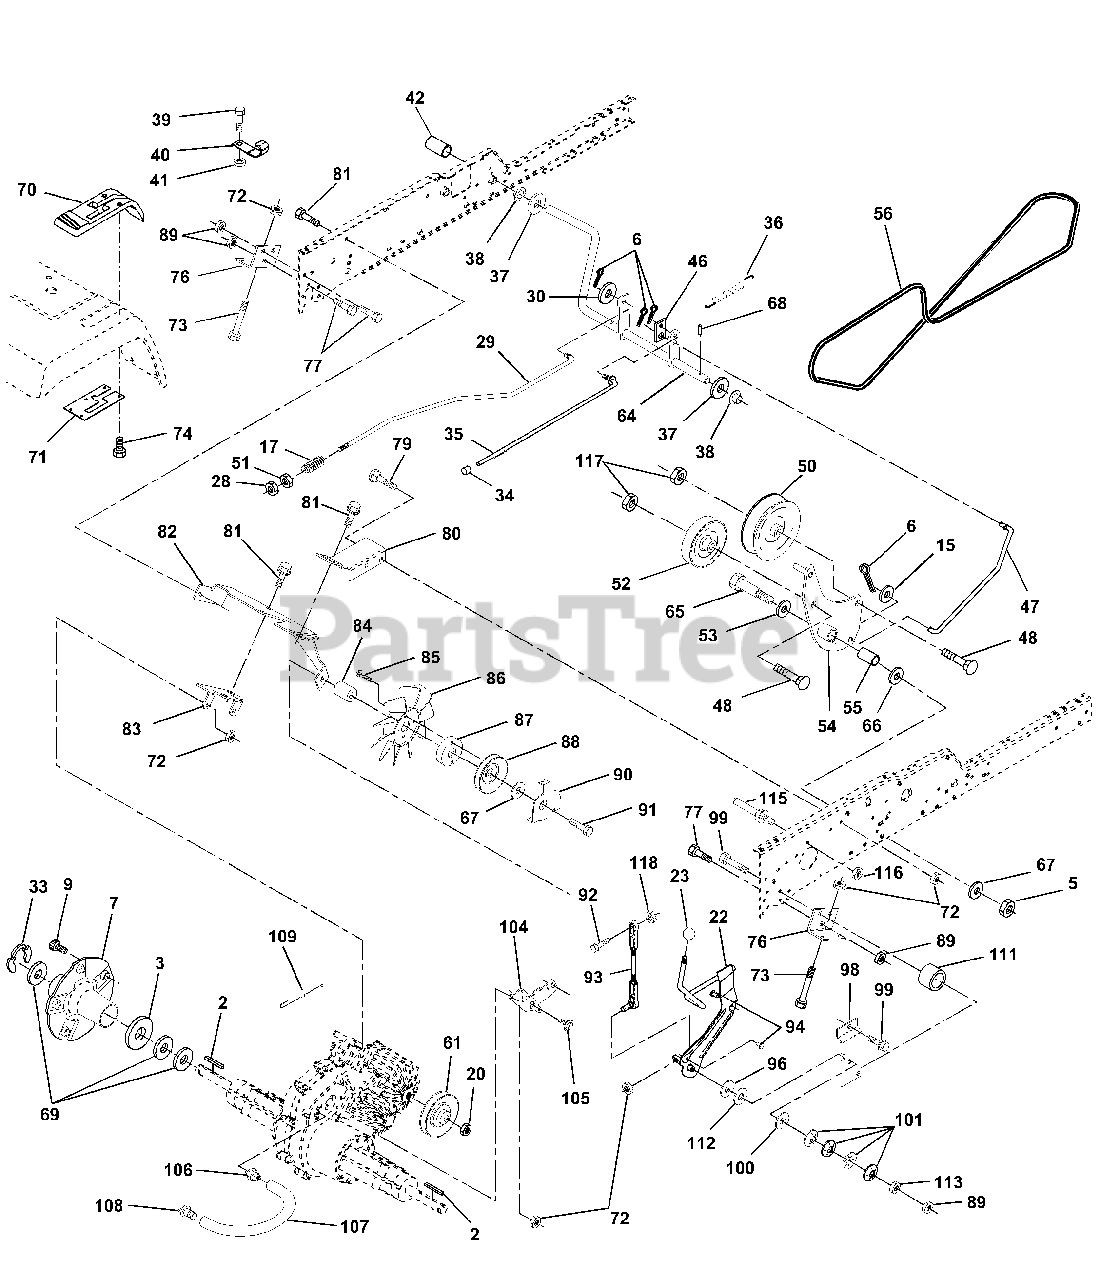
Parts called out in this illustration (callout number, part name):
2	Key 1/4 x 2.5
3	Washer Thrust Axle Harden
5	Nut Crownlock 3/8-16
6	Pin Cotter 1/8 x 3/4
7	Wheel Hub Asm.
9	Bolt Hub
15	Washer 13/32 x 13/16 x 16 Ga.
17	Spring Rod Brake
20	Nut Hex Jam Toplock 1/2-20
22	Shaft Arm Asm
28	Nut, Hex Jam 3/8-16
29	Brake Rod
30	Washer 13/32 x 1 x 16Ga
34	Cap Plunger
35	Rod Parking Brake
36	Spring Drive Ground
37	Washer 25/32 x 1-1/4 x 16 Ga.
39	Screw Fin #10-24 x 1
40	Actuator Interlock Switch
41	Nut Toplock #10-24 UNC
42	Cover Pedal
46	Retainer Spring
47	Clutch Rod
48	Bolt Carriage 3/8-16 x 1-1/2 Gr. 5
50	Pulley Idler Flat
51	Nut Lock Hex 3/8-16
52	Pulley Idler Grooved
53	Washer Hardened
54	Clutch Arm Asm
55	Bearing, Idler
61	Pulley Transaxle
64	Shaft Asm Brake Parking Clutch
65	Bolt Shoulder
66	Washer Hardened
67	Washer 13/32 x 13/16 x 12 Ga
69	Washer
70	Console Hydro Fender
71	Plate Console Shift
72	Nut Crownlock 5/16-18
73	Bolt Hex FLGHD 5/16-18 x 3 Gr 5
74	Screw, Hex Wsh Hi-Lo 1/4-1/2
76	Bracket Transaxle
77	Bolt Fin Hex 7/16-14 x 1
79	Bolt Carriage 5/16-18 x 5/8
80	Bracket Torque RH
81	Screw 3/8-16 x 3/4
82	Bracket Mount Torque/Fan
83	Strap Torque Mid
85	Screw #10-24 x 1-1/4
86	Fan 7" Hydro
87	Adapter Fan
88	Pulley Idler
89	Nut, Crownlock 7/16-14
90	Keeper Belt
91	Screw Thdrol 3/8-16 x 2-3/4
92	Bolt Fin Hex 5/16-18 x 1.75
93	Link Shift Asm
94	Fastener Christmas Tree
96	Washer Nickel Plated
98	Bracket Shift
99	Screw 3/8-16 x 1-1/2
100	Washer Compression
101	Washer Bellville
104	Bracket Idler
105	Screw Tap 1/4-20 x 1/2
106	O-Ring Asm. Hydro Gear
107	Line Fuel Hydro
108	Cap Vent
109	Spring Return Brake
111	Spacer Shift Lever VGTH
112	Washer Nylon High Temp
113	Nut Hex ASF 7/16-14 UNC
115	Keeper Belt Gnd Dr.
116	Nut Lock Hex Flange 5/16-18
117	Nut Lock Flg. 3/8-16 UNC
118	Nut Lock Hex w/Ins. 5/16-18 Unc
